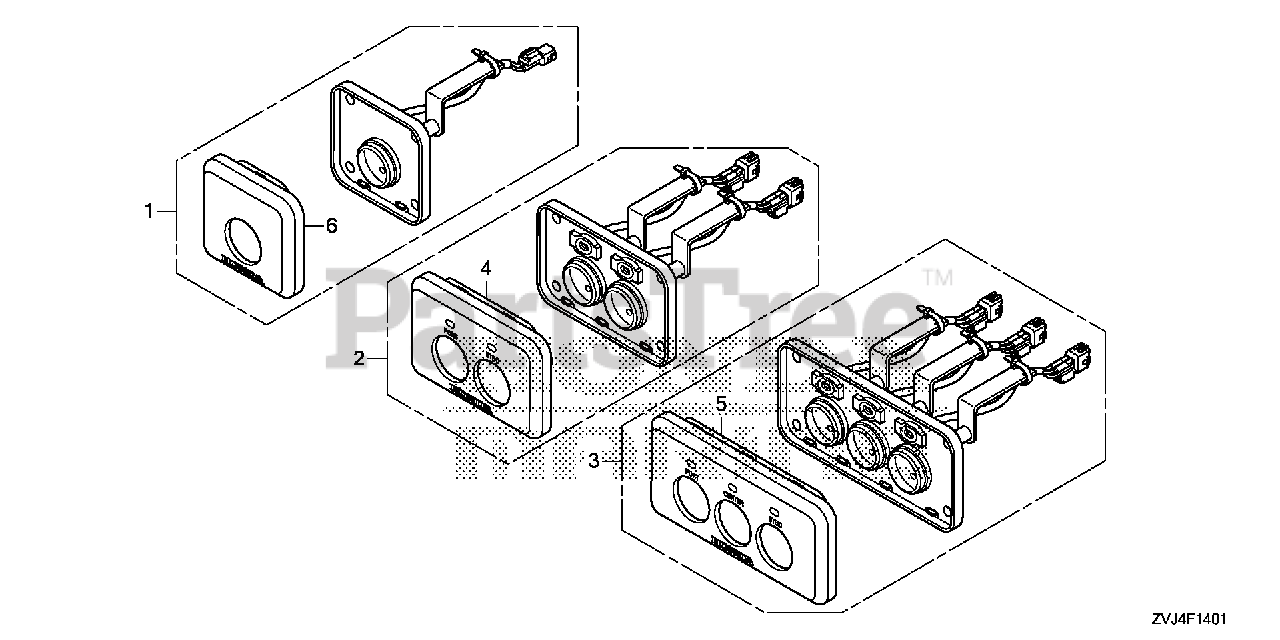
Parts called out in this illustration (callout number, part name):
1	PANEL ASSY., START STOP (ALL)
2	PANEL ASSY., START STOP (TWIN)
4	PANEL, START STOP (TWIN)
6	PANEL, START STOP (ALL)
